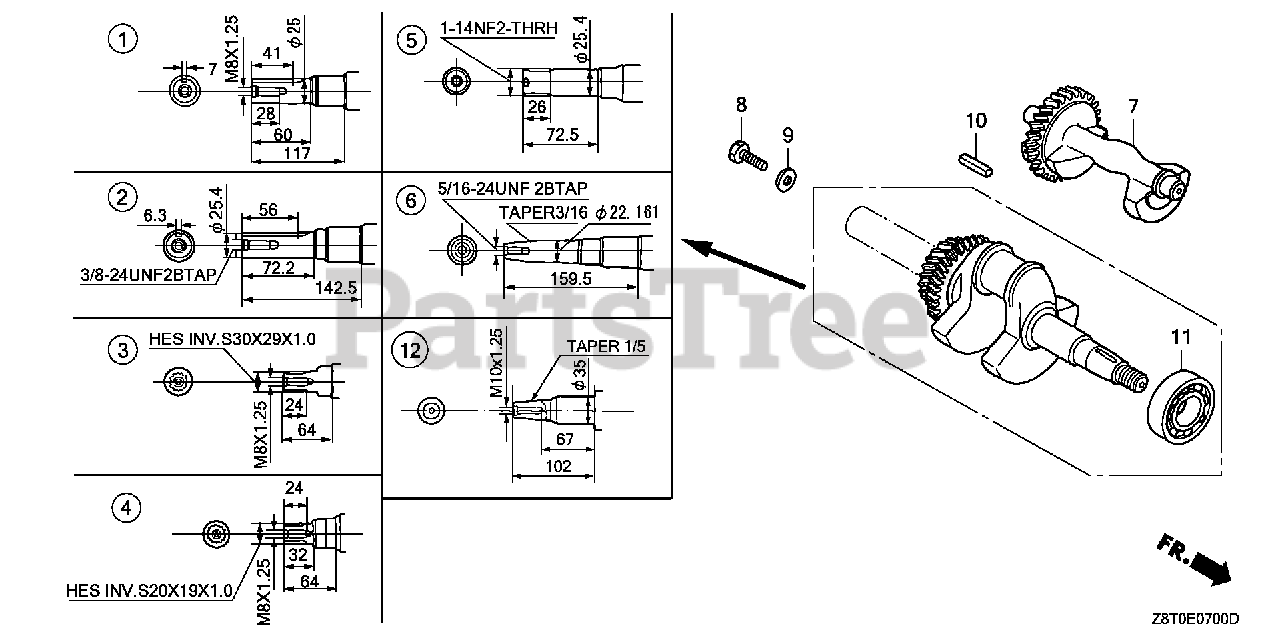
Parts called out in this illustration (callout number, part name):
4	CRANKSHAFT
7	WEIGHT, BALANCER
8	BOLT, FLANGE (8X25)
9	WASHER (8MM)
11	BEARING, RADIAL BALL (6207)
